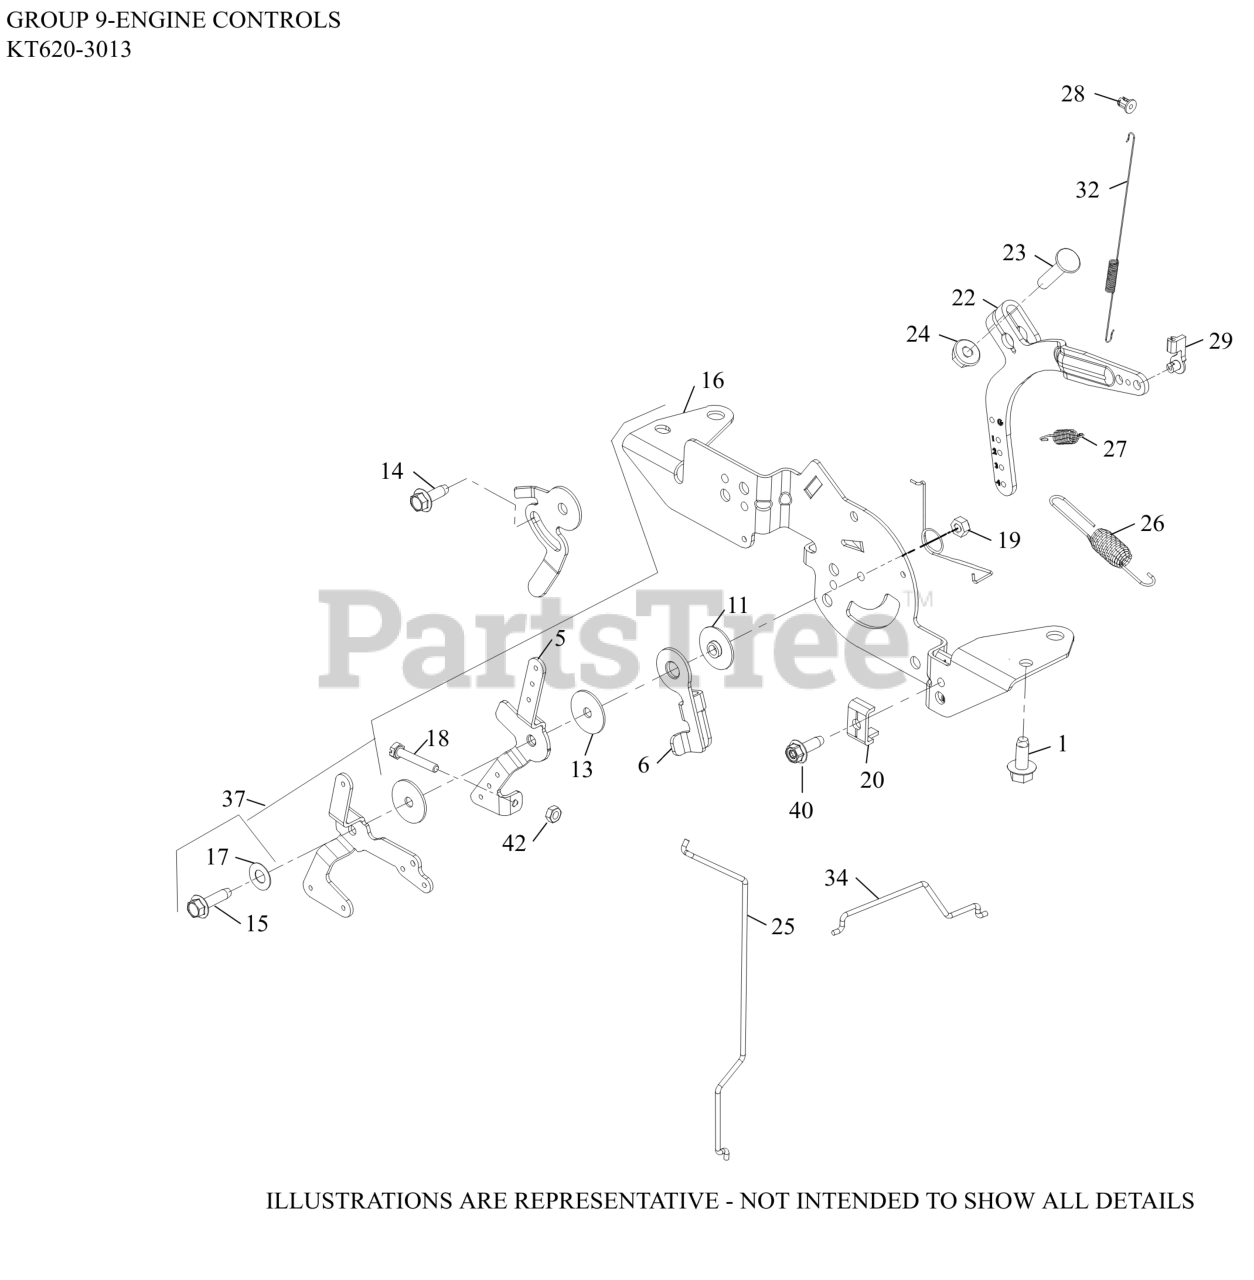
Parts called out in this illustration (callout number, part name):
1	SCREW, THREAD FORMING
5	LEVER, THROTTLE CONTROL
6	LEVER, THROTTLE ACTUATOR
11	SPACER, CONTROL ASSEMBLY
13	WASHER, FLAT 5 MM
14	SCREW, THREAD FORMING
15	SCREW, THD FRM-USE 25 086 473-S
16	BRACKET, SPEED CONTROL
17	WASHER, SPRING 1/4"
18	SCREW, SLT HD CAP M4X0.7X25
19	NUT, LOCK M5X.8
20	CLAMP, CABLE-(#2523753S)
22	LEVER, GOVERNOR - (#2409069S)
23	BOLT, RD HD SQ NECK M6X1.0X25
24	NUT, FLG M6X1.0
26	SPRING, GOVERNOR (ORANGE)
27	SPRING, GOVERNED IDLE
28	BUSHING, LINKAGE RETAINING
29	BUSHING, THROTTLE LINKAGE
32	SPRING, LINKAGE
34	LINKAGE, THROTTLE
37	SPEED CONTROL, ASSEMBLY
40	SCREW, THREAD FORMING
42	NUT, M4X0.7
